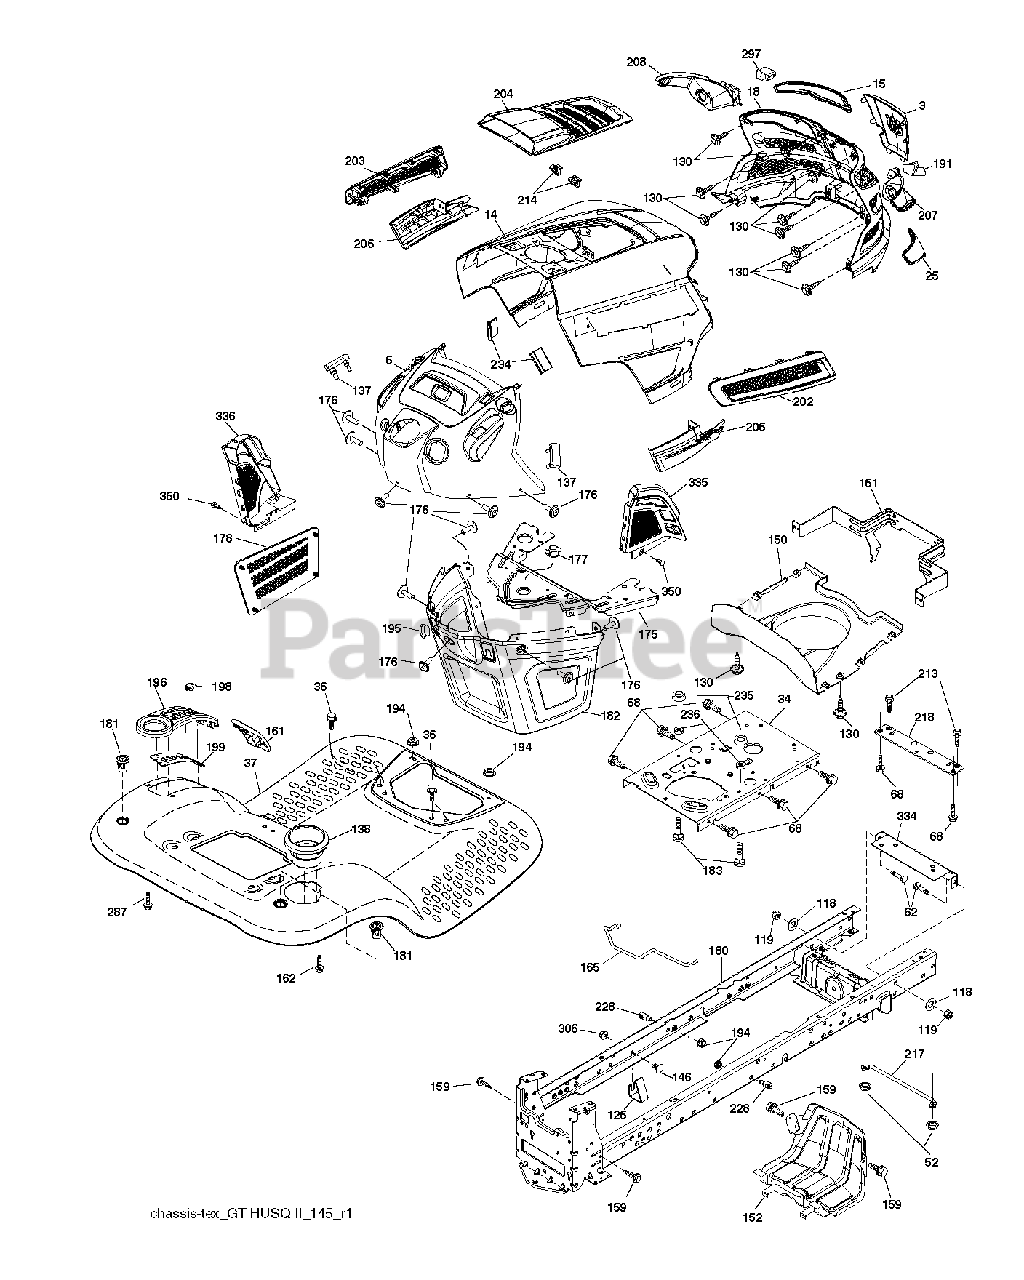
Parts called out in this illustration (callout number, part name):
3	APPLIQUE.SUBASM.GT.HUSQ.II
5	DASH.UPPER.ASSY.GT2.GREY
14	HOOD.ASM.HUSQVARNA.GT.TEX.ORAN
15	LENS.HEADLIGHT.LH.GTII.2011
18	GRILLE.SUBSTRATE.2011.
25	LENS.HEADLIGHT.RH.GTII.2011
34	PLATE.ENGINE.WELDED.CHASSIS
36	SCREW 5/16"
37	FENDER.ERGO.LT.W/CPH.W/FW.ORNG
52	LOCKNUT
62	BOLT D
68	SCREW LT
118	WASHER
125	CLIP.FUEL.LINE
130	SCREW.#10 X 0.750.BOS
137	BUMPER DASH
138	HOLDER.CUP.LT.GREY
146	BOLT.RDHD.SHT.SQNK.3/8-16X5/8
150	AIR.DUCT.GTV2(2.54"RING HEIGHT
151	BRACKET.PIVOT.HOOD.GT.HUSQ.II
152	SHIELD.BROWNING.PNT.GT.V2
159	SCREW, 3/8-16X3/4
161	WINDOW.FUEL.LT.HUSQ.TEX.498
162	SCREW.HI-LO.CONSOLE
165	SUPPORT.TANK.REAR.W/TEX
175	PLATE.CROSSMEMBER.HUSQ
176	SCREW.#10-24X5/8.RN.QU
177	BUSHING, STEERING
178	CARGO.ASM.NET.TXGT.W/C
180	CHASSIS
181	BUSHING.MNT.FEND.CRGO.TEX.49
182	DASH.LOWER.COMMON.12V.ADAPTOR
183	BOLT.5/16-18X1-1/4 FULL THD
191	INSERT.REFLECTIVE.RH.HUSQ.GTII
194	NUT LOCK HEX FLANGE 5/16-18
195	PLUG.HOLE.DASH.LOWER.12V.BLK
196	DECKLFT.CONSOL FULL ASSM GREY
198	INDICATOR.DECK.LIFT.RED
199	PLATE.DECK.LIFT.HUSQ.LT
202	VENT.SIDE.RH.GT.HUSQ.II.
203	VENT.SIDE.LH.GT.HUSQ.II.498
204	VENT.TOP.HUSQ.GT2
205	SIDE.TRIM.RH.GT.HUSQ.II
206	SIDE.TRIM.LH.GT.HUSQ.II.GRAY
207	BEZEL LIGHT.RH.GT.II.MYLAR
208	BEZEL LIGHT.LH.GT.II.MYLAR
213	BOLT
214	CLIP.RETAINER.TINNER.
217	ROD.PIVOT.HOOD
218	X-PIECE.HOOD.STOP.NON/
228	STUD.FASTNER.W/ANTI-ROTATE
234	BUMPER.HOOD.TEX.HUSQVARNA
235	SPACER FENDER
236	NUT.CENTERLOCK.5/16-
287	SCREW 1/4X20
297	INSERT.REFLECTIVE.LH.HUSQ.GTII
306	NUT LOCK FLG 3/8-16 UNC
334	BRACKET.ENGINE
335	COVER.LOWER.DASH.RH.BLACK
336	COVER-LH.LOWER.DASH.GT2.BLACK
350	CLIP.X-MAS.TREE
